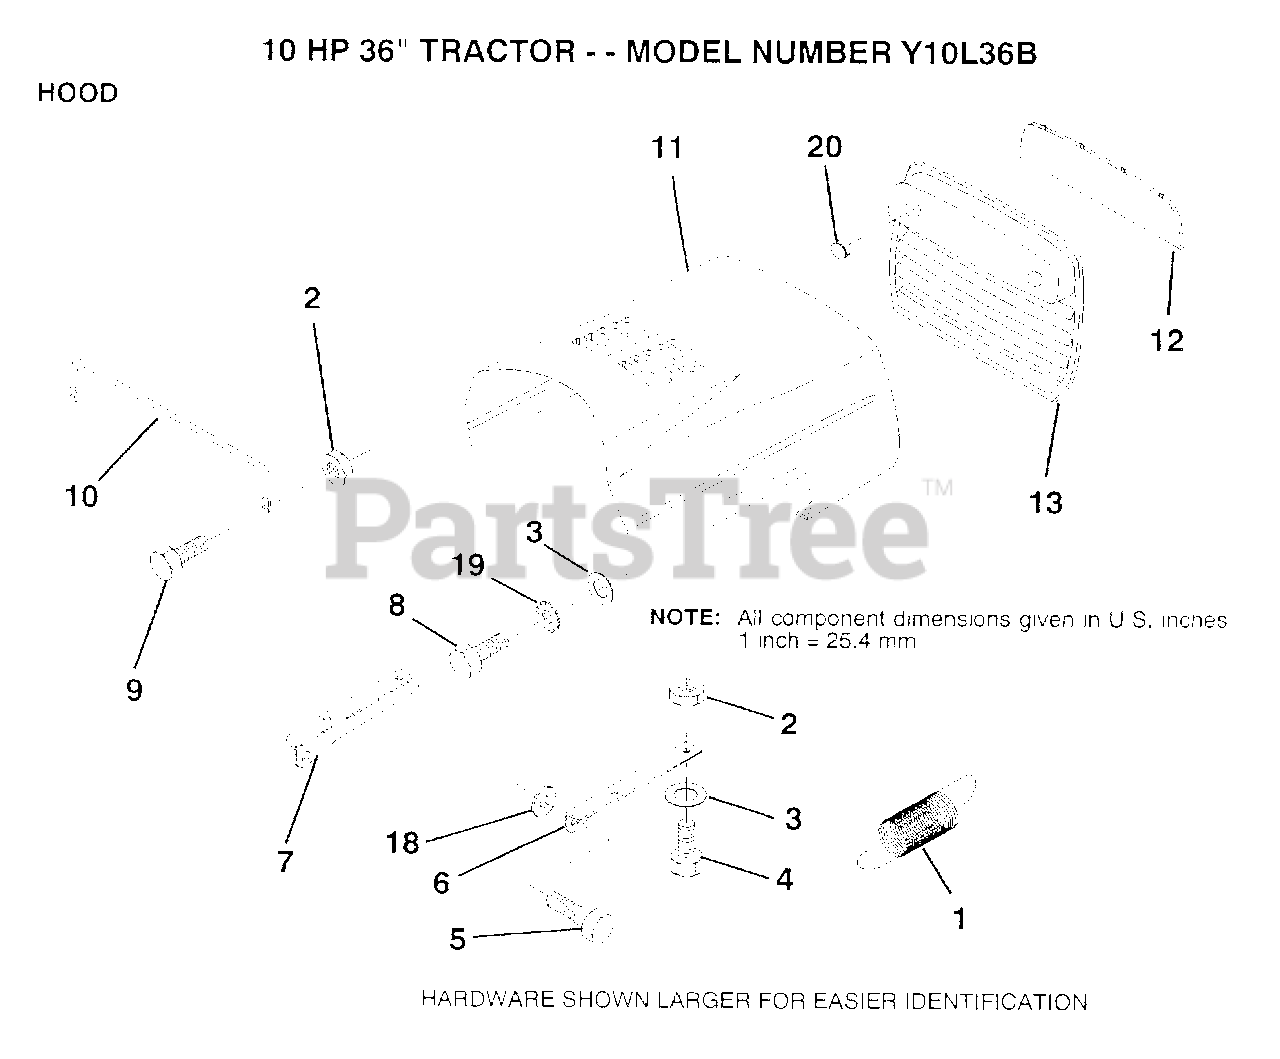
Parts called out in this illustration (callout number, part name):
1	EXT SPRING
2	NUT
3	WASHER
4	BOLT
6	BRKT HOOD RH
7	BRKT HOOD LH
10	"BRACE,HOOD"
11	HOOD
12	LENS
13	GRILL
18	WASHER
19	LOCKWASHER GT
